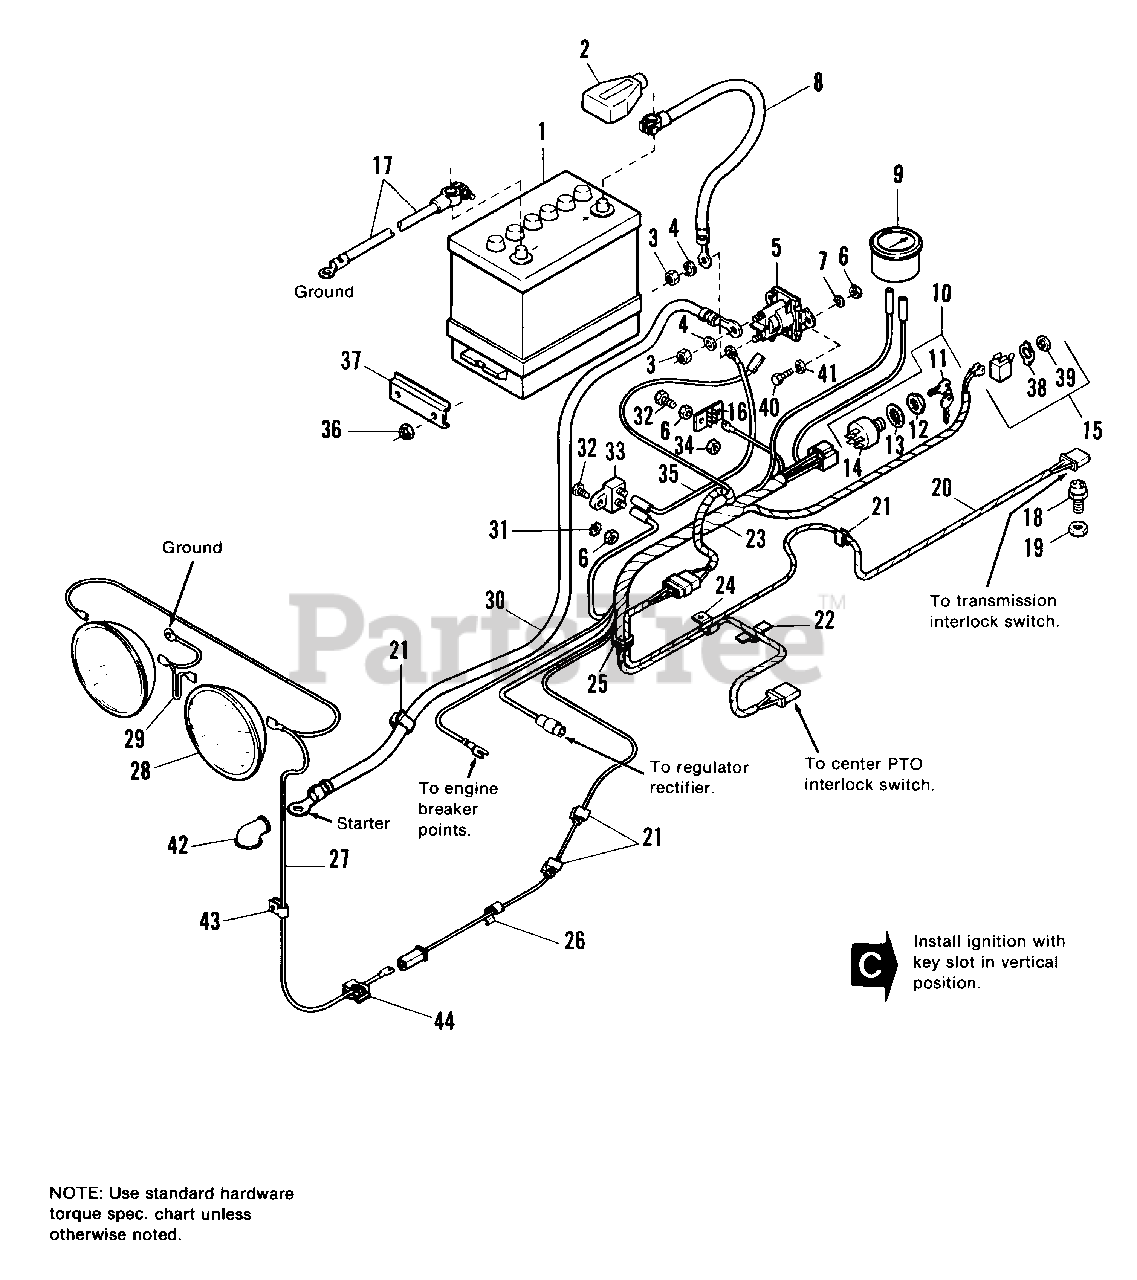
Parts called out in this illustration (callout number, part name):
1	BATTERY (Includes Decal)
2	CABLE BOOT, Insulating
3	NUT, Hex, Full, 5/16-18
4	LOCKWASHER, 5/16
5	SOLENOID, Starter
6	NUT, Hex, Full, 1/4-20
7	LOCKWASHER, 1/4 (Qty. 3 on 7117)
8	CABLE (Battery to Solenoid)
10	SWITCH & KEY ASSY., Ignition
11	KEY SET (2)
12	NUT, Special
13	LOCKWASHER, Int., 5/8
15	SWITCH, Toggle
16	BOARD, Terminal
17	CABLE (Battery to Ground)
18	SWITCH, Interlock
19	NUT, Pal
20	WIRE ASSY.
21	CLIP, Tinnerman
22	CLIP, Tinnerman
23	HARNESS ASSY.
24	CLIP, Cable
26	CLIP, Tinnerman
28	LAMP, Sealed Beam, G.E. #4411-1
29	WIRE ASSY.
30	CABLE (Solenoid to Starter)
31	LOCKWASHER, 1/4
32	CAPSCREW, Hex Hd., 1/4-20 x 5/8
33	BREAKER, Circuit
34	LOCKNUT, Hex, 1/4-20
36	LOCKNUT, Elastic, 5/16-18
39	NUT, Switch
40	CAPSCREW, Hex Hd., 1/4-20 x 3/4
41	WASHER, Special
42	COVER, Terminal
43	CLAMP, Wire
44	CLIP, Speed Cable
